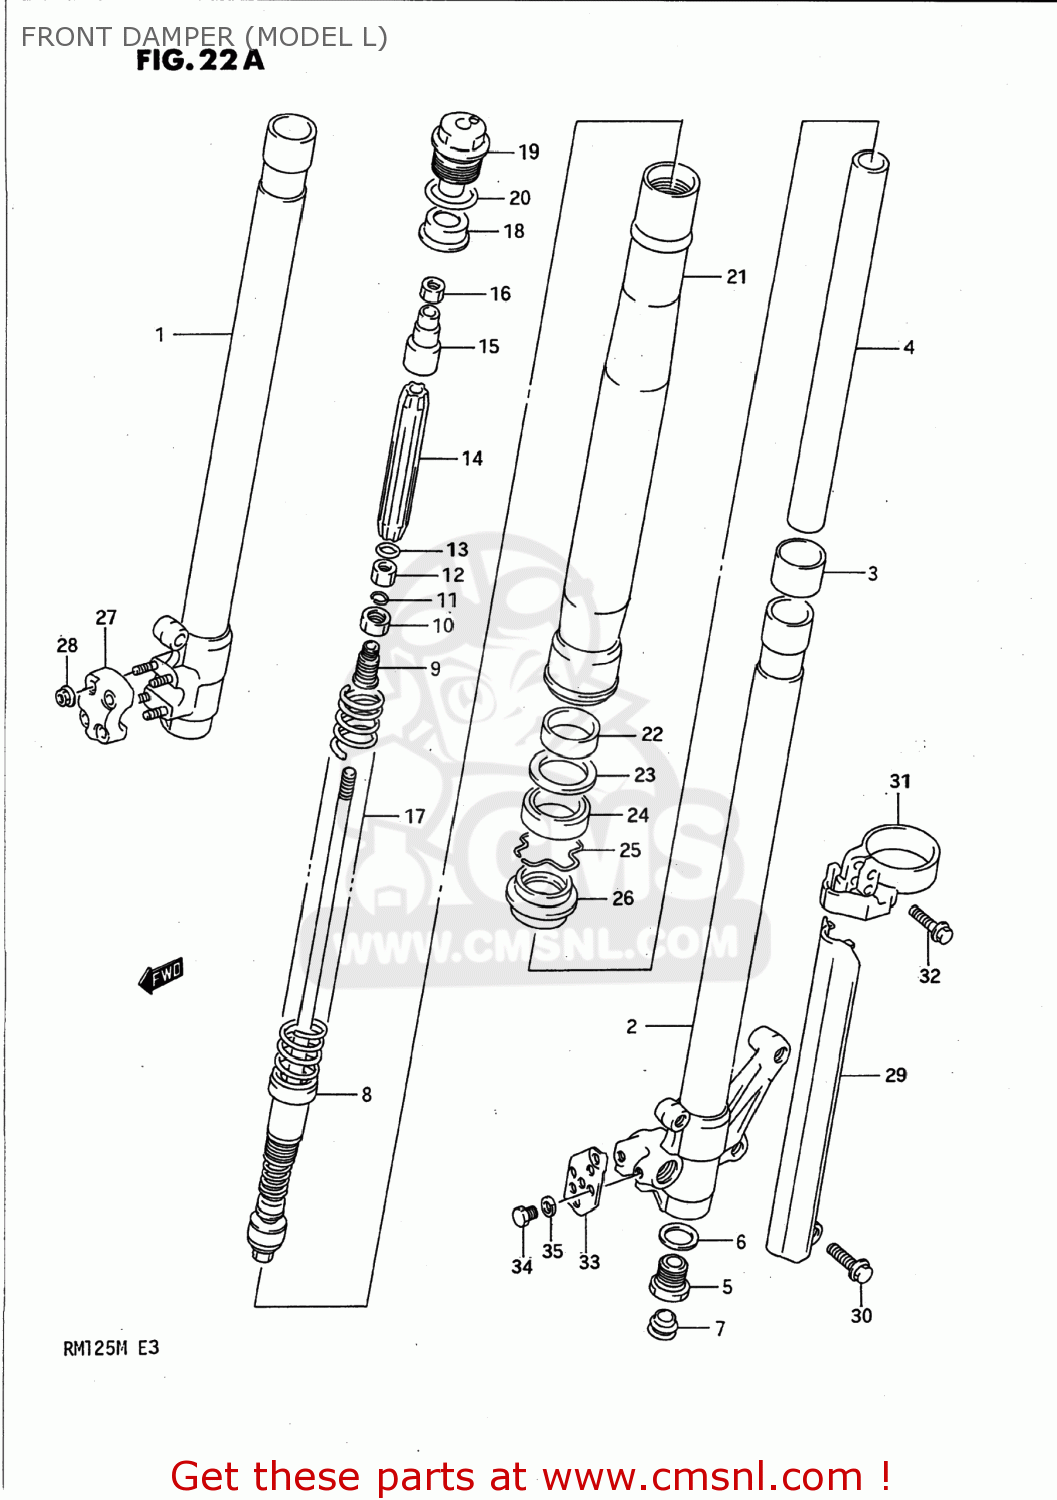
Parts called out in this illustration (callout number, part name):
1	TUBE,INNER,RIGHT
2	TUBE,INNER,LEFT
3	PISTON
4	CYLINDER
5	BOLT,CENTER
6	GASKET (NAS)
7	CAP,RUBBER
8	ROD ASSY,PISTON
9	HOLDER,PIECE
10	PIECE,OIL LOCK
11	RING,SNAP
12	NUT,PIECE
13	O-RING
14	GUIDE,SPRING
15	SPACER,SPRING GUIDE
16	NUT
17	SPRING
18	GUIDE,SPRING WASHER
19	CAP,FORK
20	O RING
21	TUBE,OUTER
22	METAL,SLIDE
23	WASHER,FORK OIL SEAL
24	SEAL,OIL
25	RING,OIL SEAL STOPPER
26	SEAL,DUST
27	HOLDER,AXLE
28	NUT
29	PROTECTOR,R
30	BOLT
31	GUIDE,PROTECTOR,R
32	BOLT, GUIDE
33	COVER,HOSE
34	BOLT 5X10
35	LOCK WASHER
